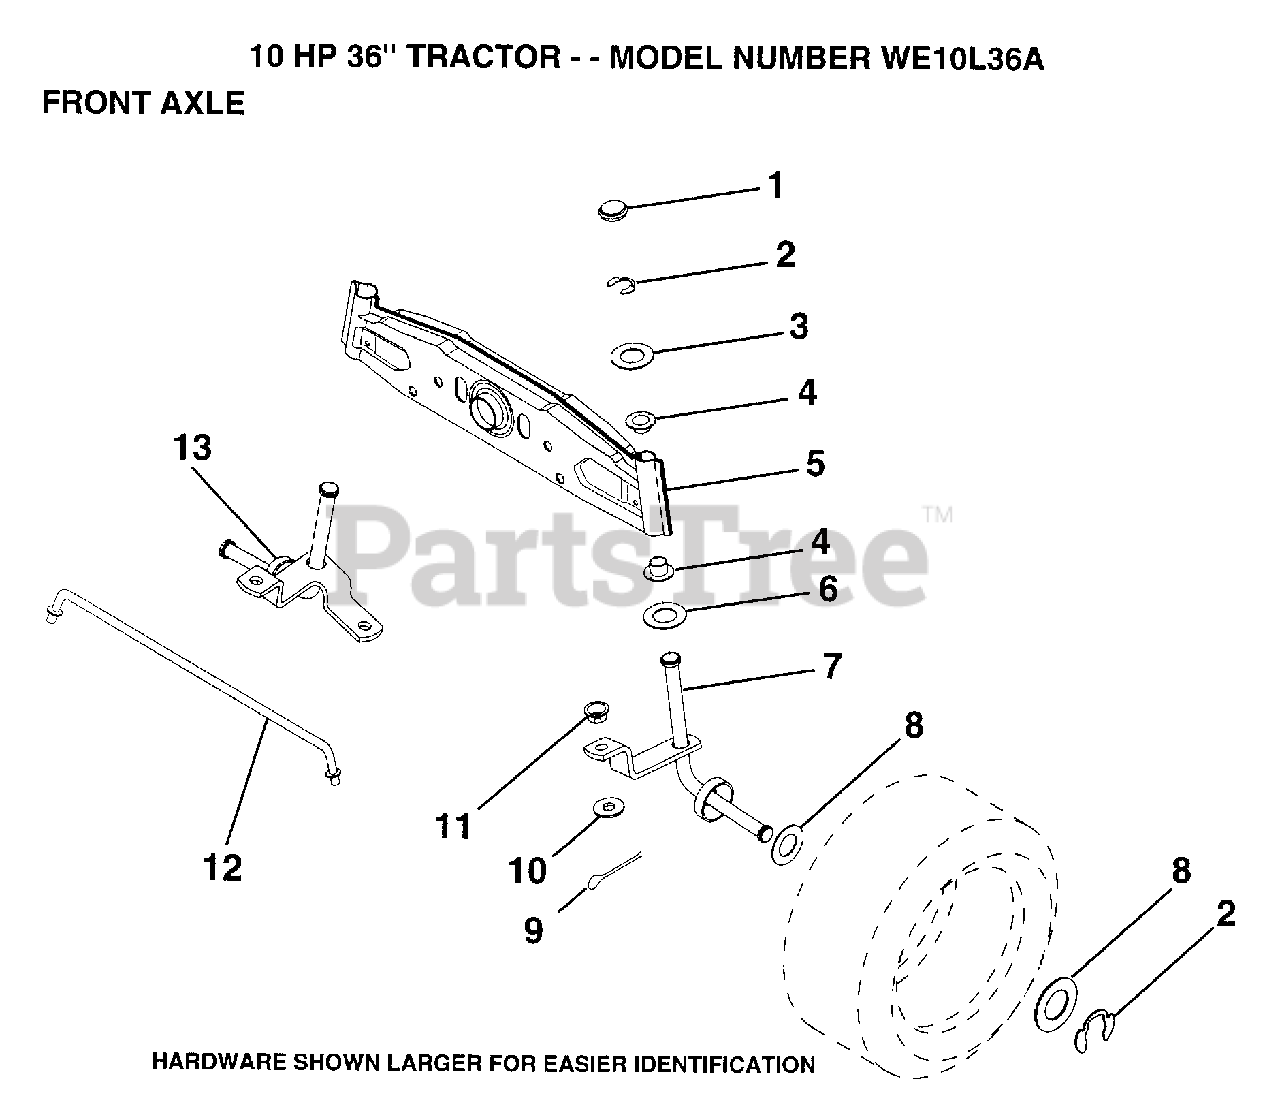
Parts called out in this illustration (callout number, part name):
1	CAP
2	RING
3	WASHER
4	NYLINER
5	AXLE FRONT
6	WASHER .T
7	SPINDLE RH
8	WASHER
9	COTTER PIN
10	WASHER
11	BUSHING.DRAGLINK
12	ROD TIE
13	SPINDLE LH
